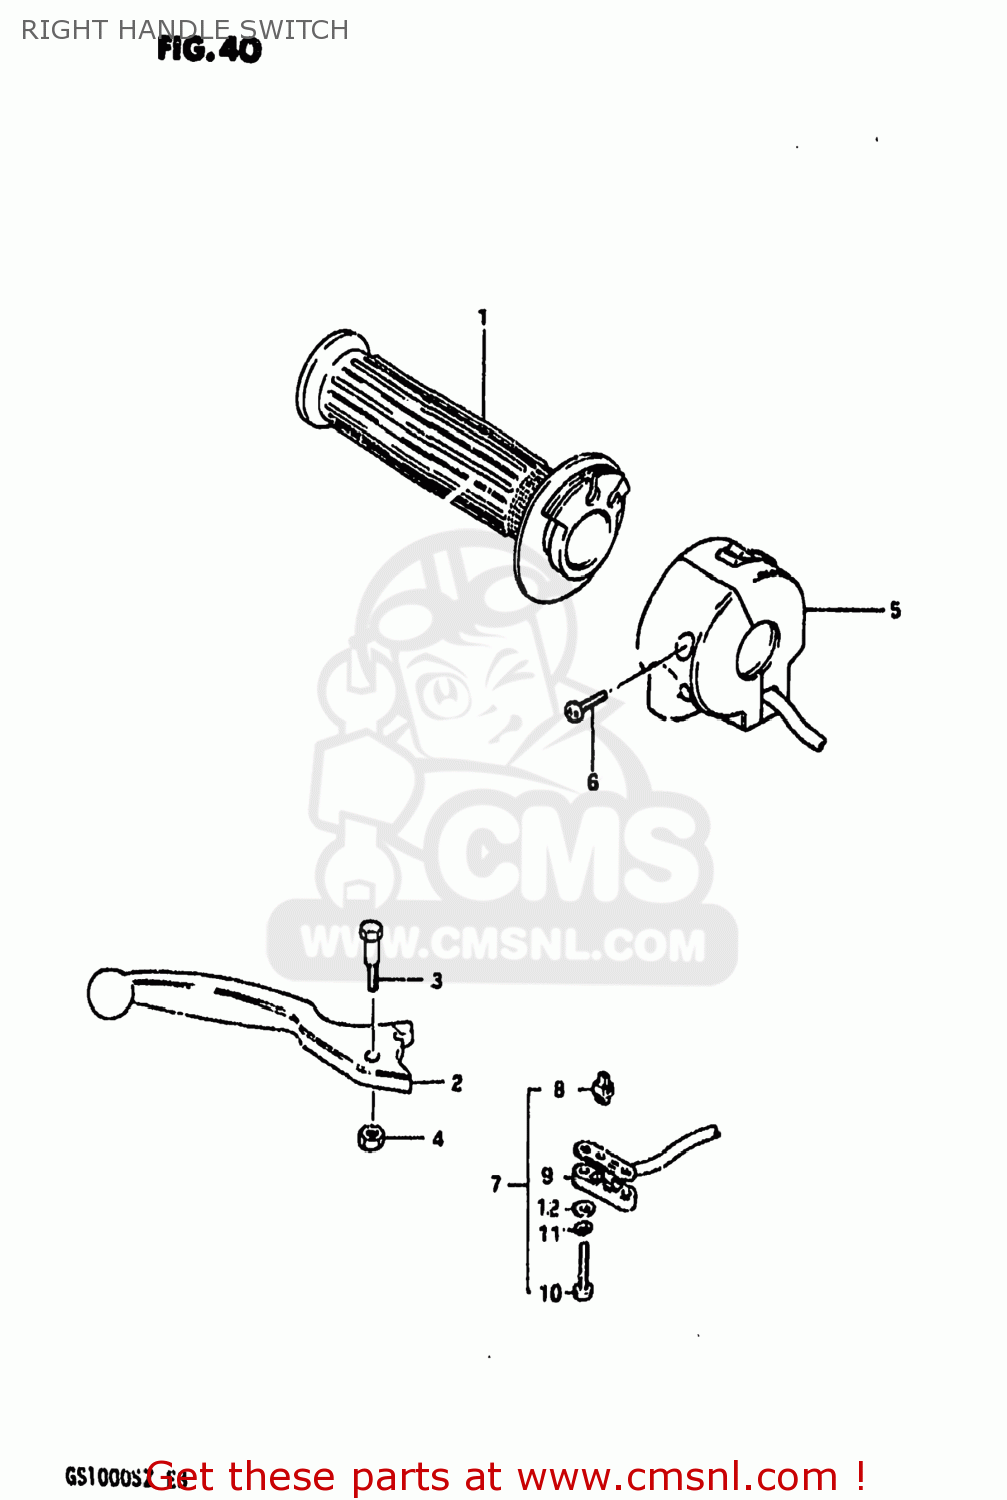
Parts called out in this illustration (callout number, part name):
1	GRIP,THROTTLE
2	LEVER,BRAKE
3	BOLT
4	NUT
5	SWITCH ASSY,HANDLE,R
6	SCREW
7	SWITCH ASSEMBLY
8	CONTACT,SWITCH
9	COVER,FR BK TERMINAL BASE
10	SCREW
11	LOCK WASHER
12	WASHER
13	SPRING,STARTER BUTTON
14	SPRING,STARTER BUTTON
15	CONTACT,STARTER BUTTON
